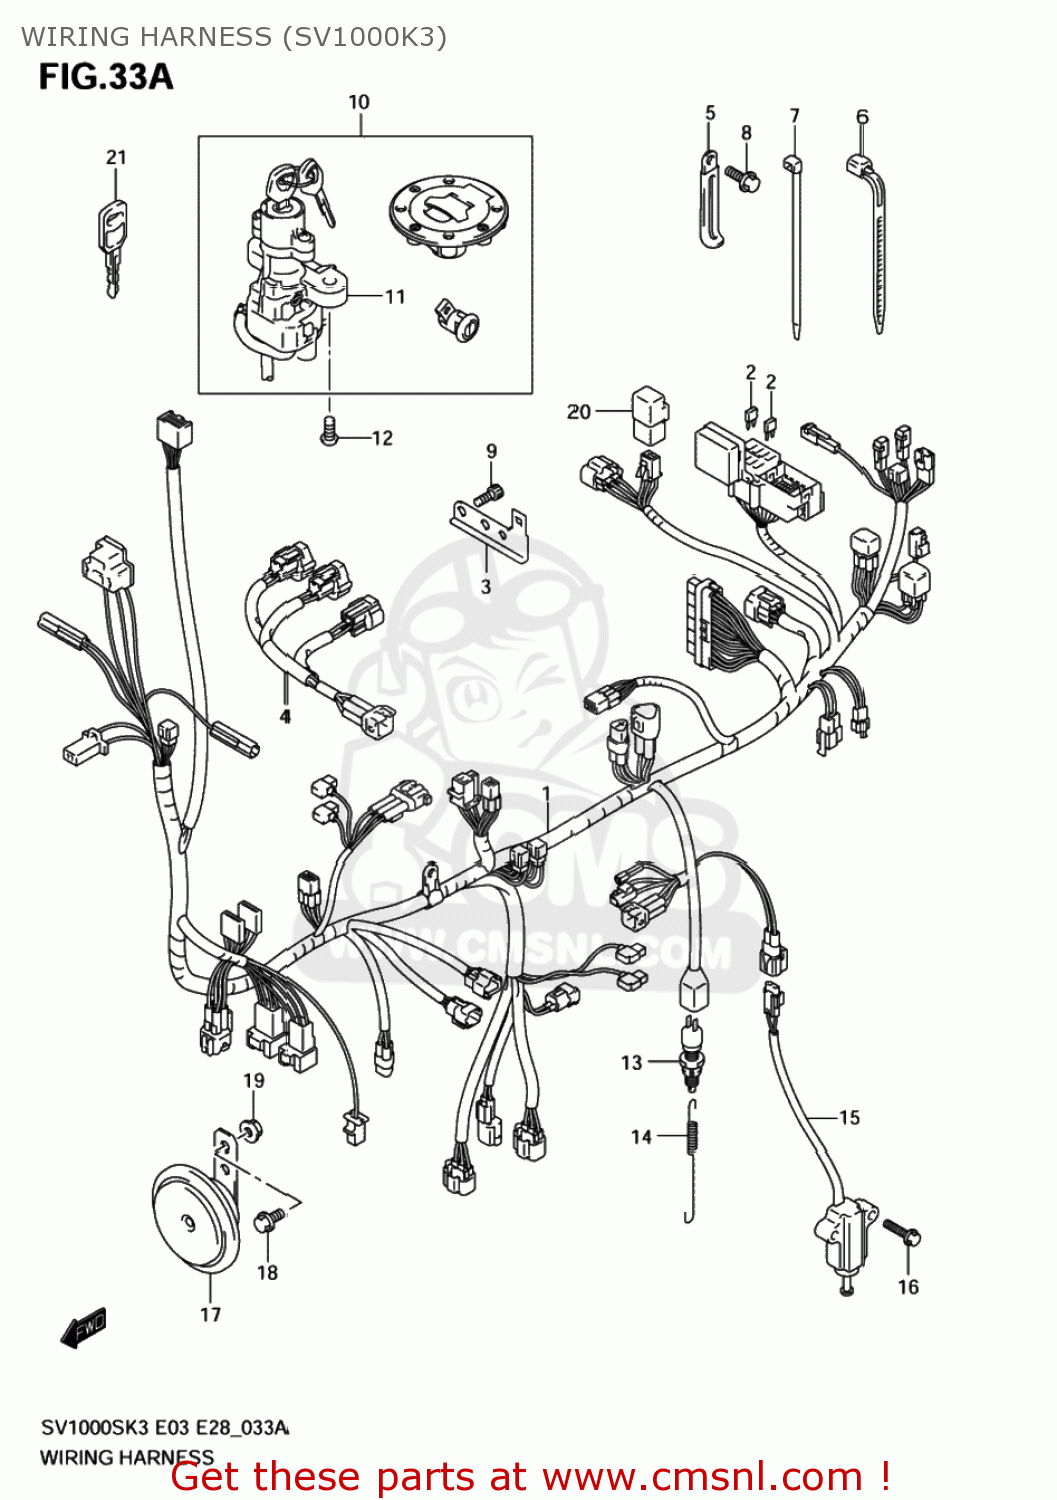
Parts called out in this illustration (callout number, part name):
1	HARNESS, WIRING NO.1
2	FUSE(10A)
3	HOLDER,COUPLER
4	WIRE,INJECTOR LEAD
5	CLAMP(L:45)
6	CLAMP(L:95)
7	CLAMP(L:145)
8	BOLT
9	BOLT,VAC.PIPE
10	LOCK SET
11	LOCK ASSY,STEE
12	BOLT(8X20)
13	SWITCH ASSY,STOP LAMP
14	SPRING
15	SWITCH ASSY,SIDE STAND
16	BOLT
17	HORN ASSY
18	BOLT
19	NUT
20	RELAY ASSY
21	KEY,BLANK
